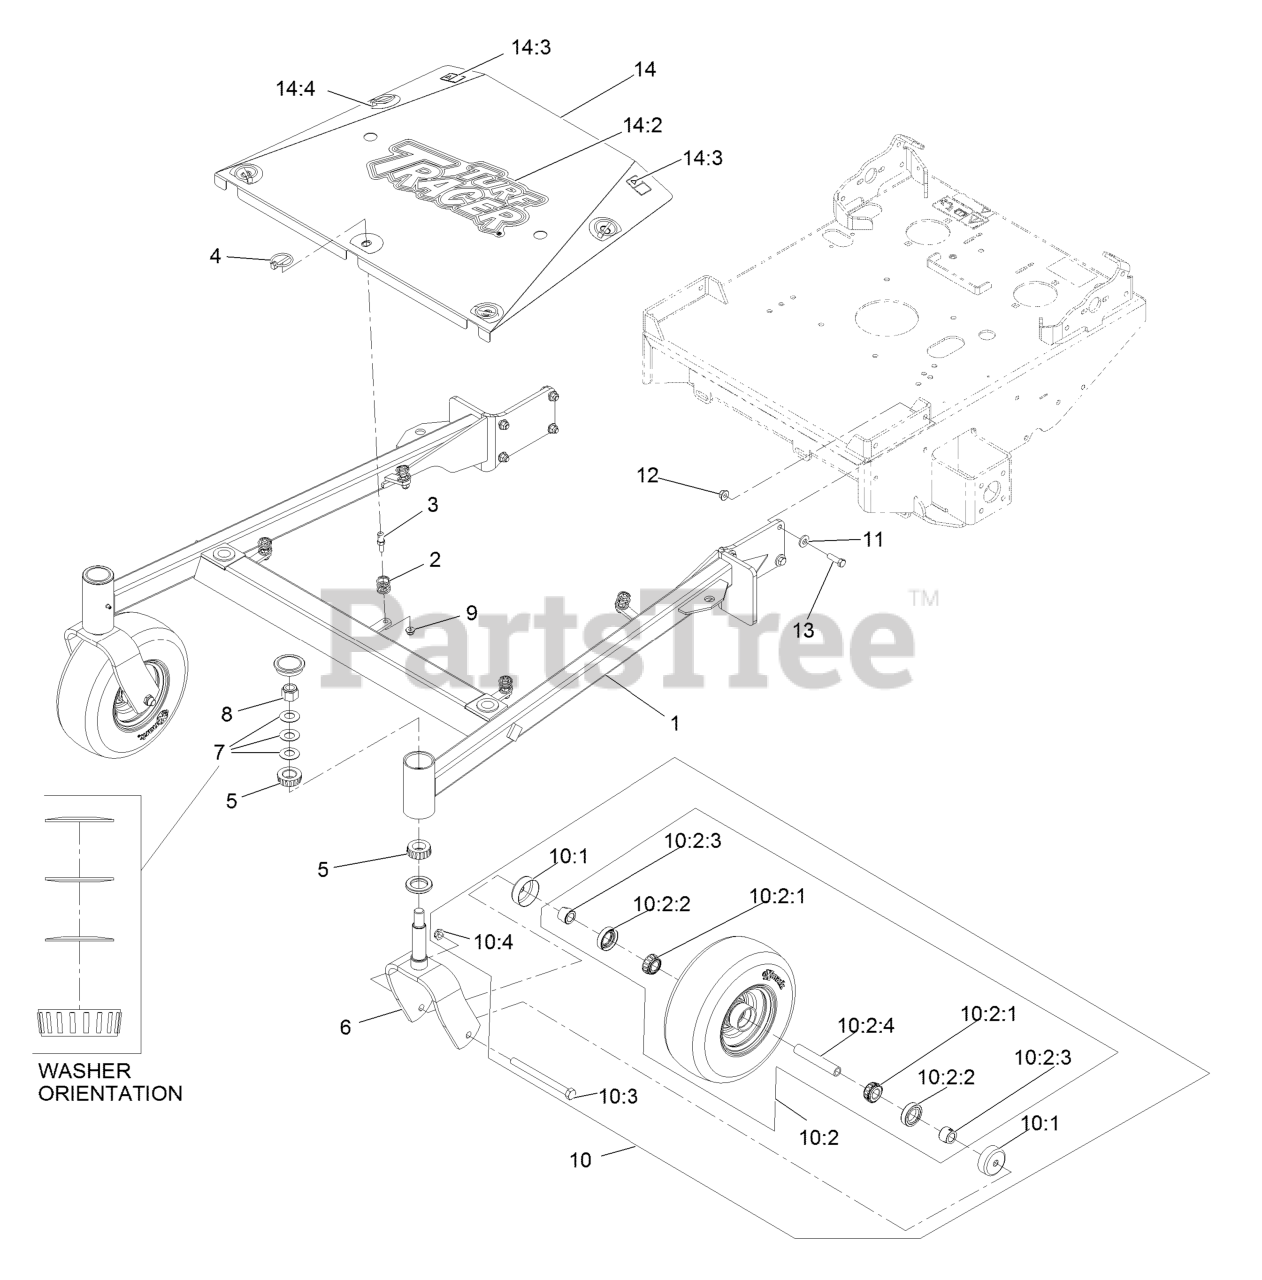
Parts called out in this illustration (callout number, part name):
1	ASM, FRONT FRAME W/ BEARI
3	PIN-SPRING
4	PIN-LYNCH
5	Cone-Bearing Tapered Roller
6	WLD, CASTER FORK
7	WASHER-BELLVILLE
8	NUT-LOCK, NI
9	NUT-HF, NI
10	ASM,WHEEL&BEARINGS
10:1	GUARD-SEAL
10:2	BEARING-CONE, TAPERED ROLLER
10:2:1	Bearing-Cone Tapered Roller
10:2:2	SEAL-CASTER
10:2:3	SPACER-NUT
10:3	SCREW-HH
10:4	NUT-HEX
11	WASHER-BELLEVILLE
12	NUT-HF, NI
13	SCREW-HH
14	ASM, CENTER SHIELD W/ DEC
14:2	DECAL,TTH MODEL
14:3	DECAL-WARNING
14:4	DECAL-SCRATCH COVER
